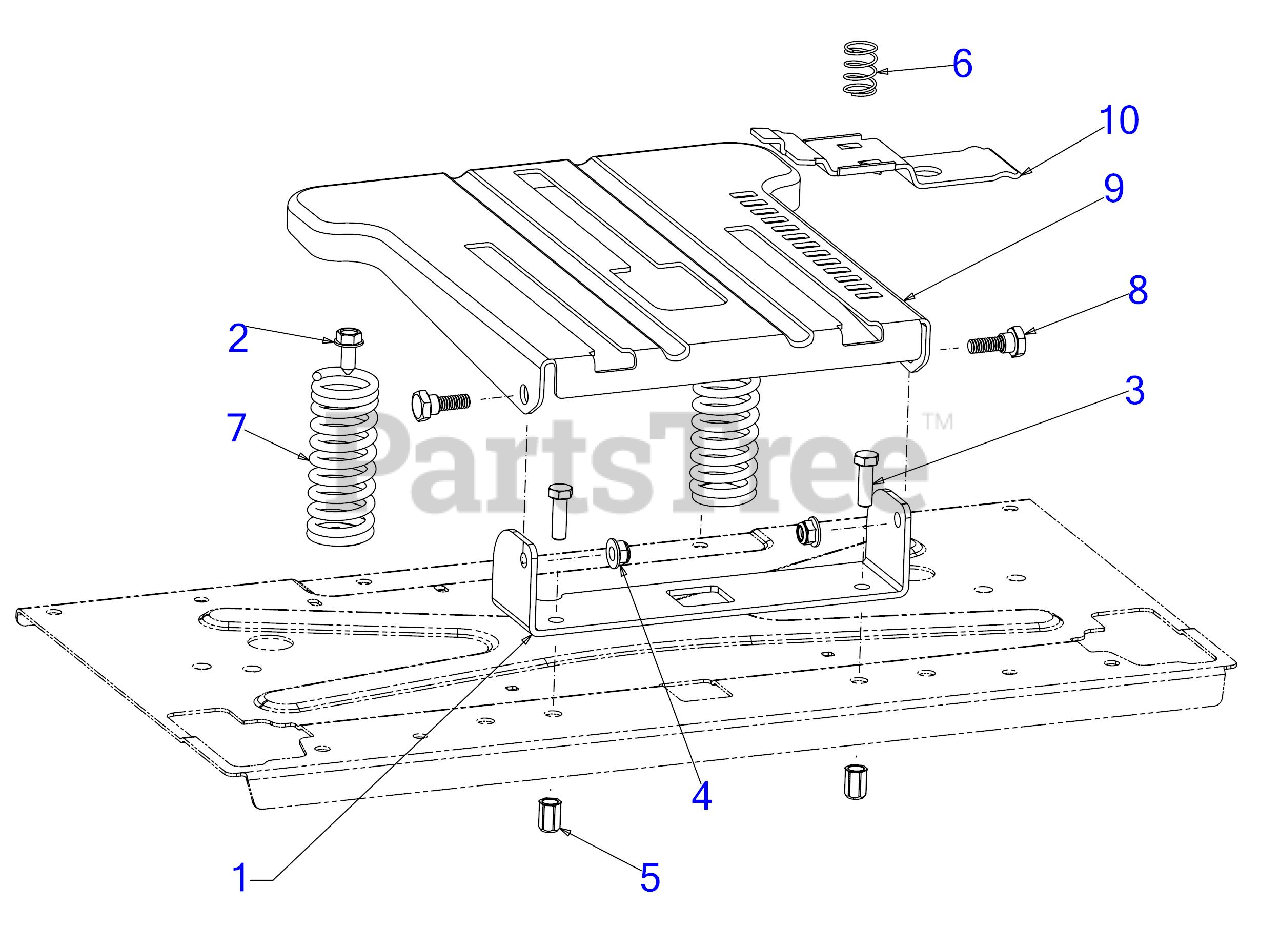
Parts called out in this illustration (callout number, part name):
2	SCREW 5/16-18 x .750
3	SCREW 5/16-18 x 1.00 GR5
4	FLANGE LOCK NUT 5/16-18
5	NUT RIVET 5/16-18
6	COMPRESSION SPRING
7	COMPRESSION SPRING
8	SHOULDER SCREW .437
10	SEAT ADJUST LEVER
